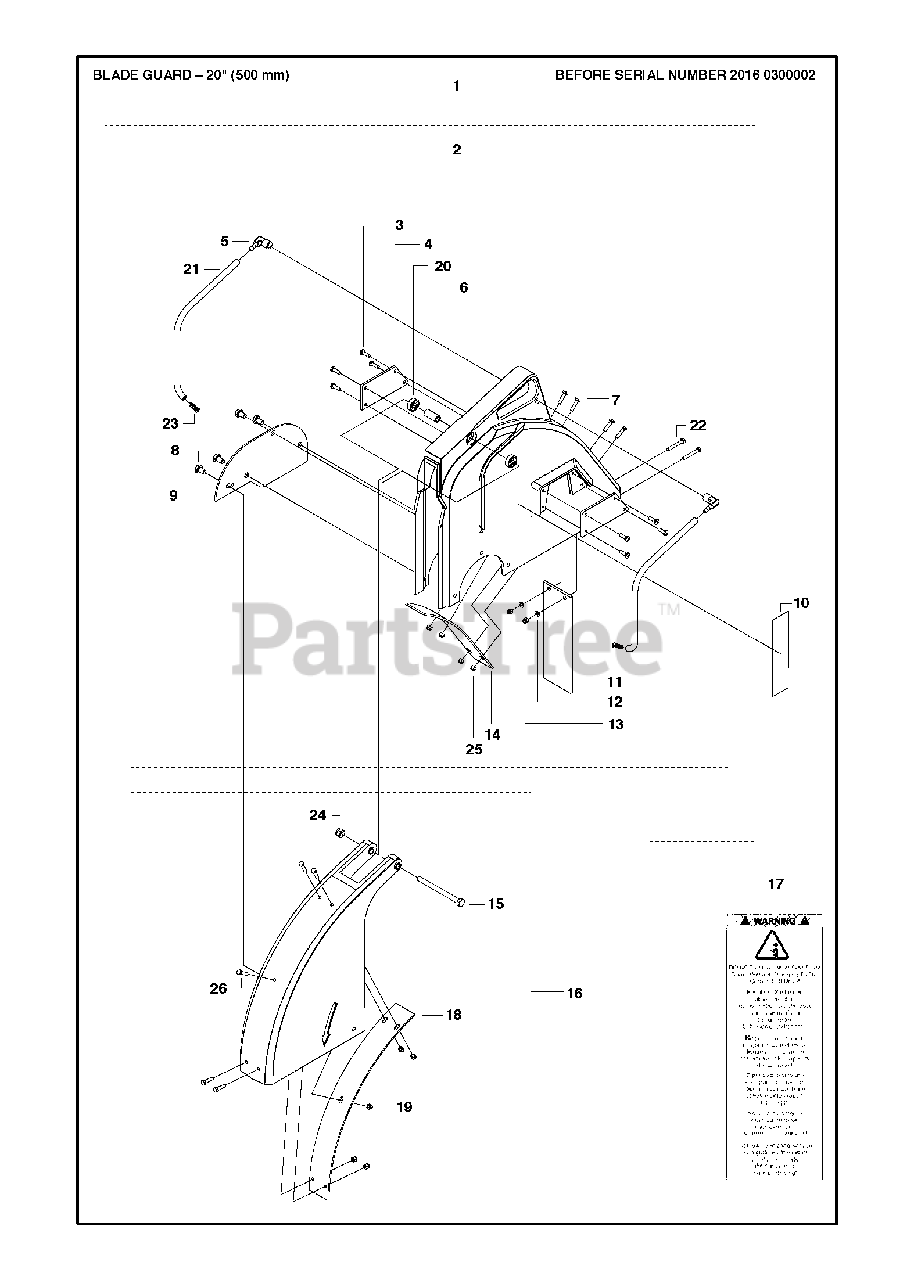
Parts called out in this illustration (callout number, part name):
4	PLATE.SPADE RETAINING.FINISHED
13	HEXAGON LOCKING NUT
19	HEXAGON LOCKING NUT
24	HEXAGON LOCKING NUT
25	HEXAGON LOCKING NUT
